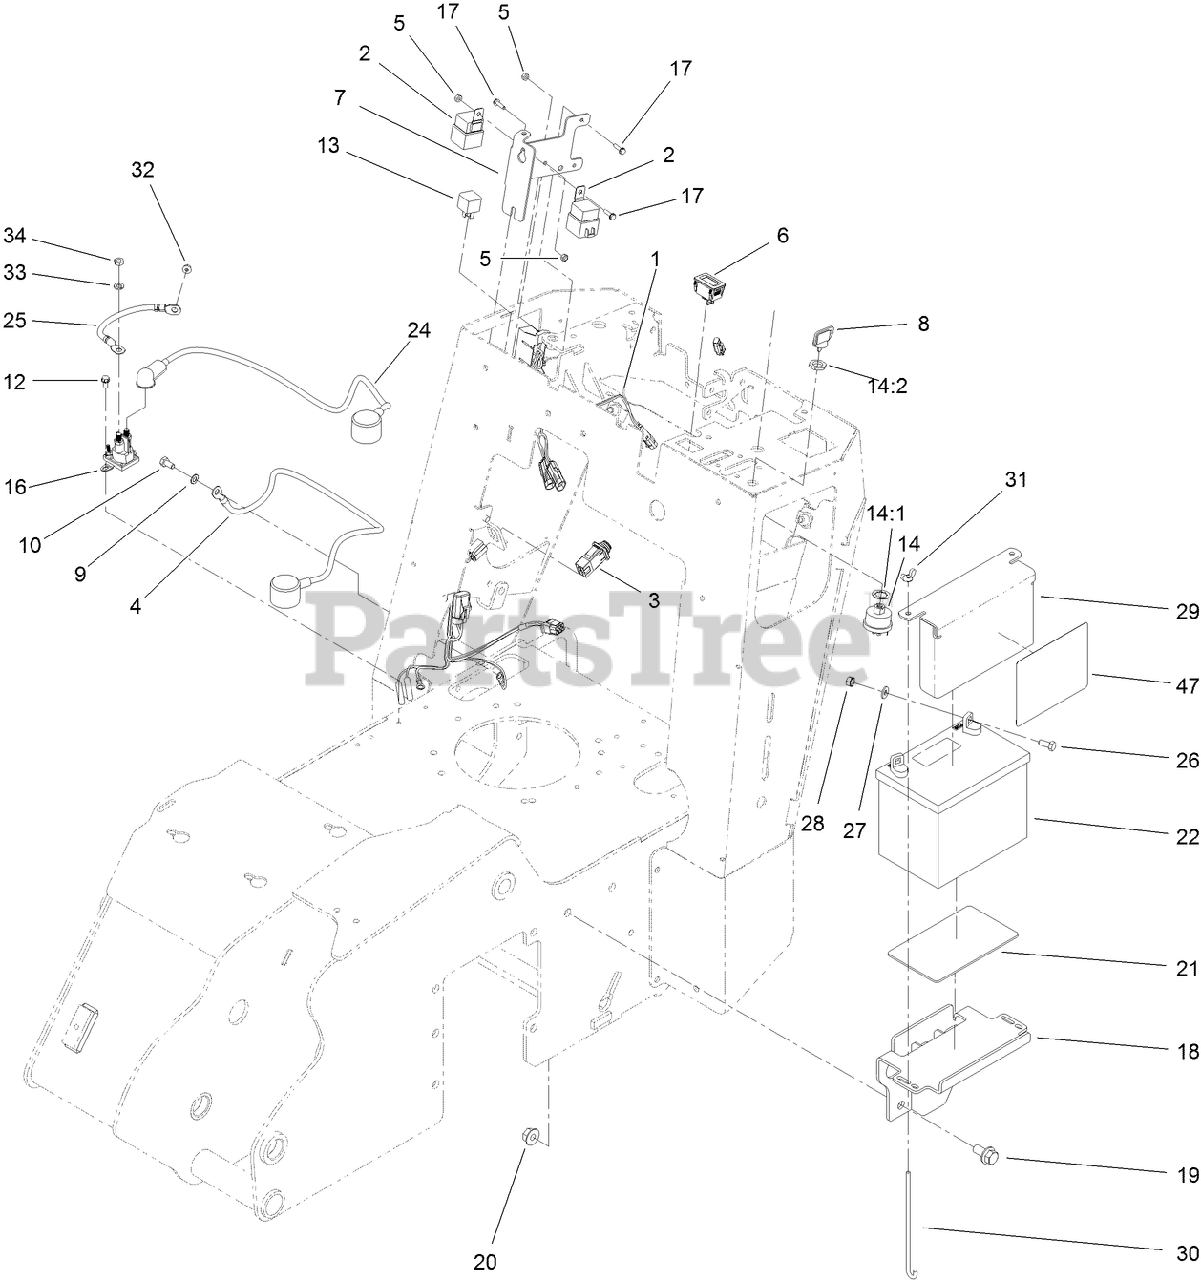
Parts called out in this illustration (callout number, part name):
1	HARNESS-WIRE
2	RELAY-MINI
3	SWITCH-PLUNGER
4	CABLE-BATTERY, NEGATIVE
5	NUT-LOCK, NI
6	HOURMETER
7	BRACKET-ELECTRICAL
8	KEY-IGNITION
9	WASHER-LOCK
10	SCREW-HH
12	SCREW-HWH
13	RELAY
14:1	WASHER-LOCK
14:2	NUT-HH
16	SOLENOID
17	SCREW-HWH
18	TRAY-BATTERY
19	SCREW-HHF
20	NUT-HHF
21	PAD-SKID, ANTI
22	BATTERY-DRY
24	CABLE-BATTERY, POSITIVE ASM
25	CABLE-BATTERY, POSITIVE
26	SCREW-HH
27	WASHER-FLAT
28	NUT-KEPS
29	PLATE-HOLD DOWN, BATTERY
30	BOLT-HOLDDOWN
31	NUT-WING
32	NUT-HF
33	WASHER-LOCK
34	NUT-JAM
47	DECAL-SERVICE
